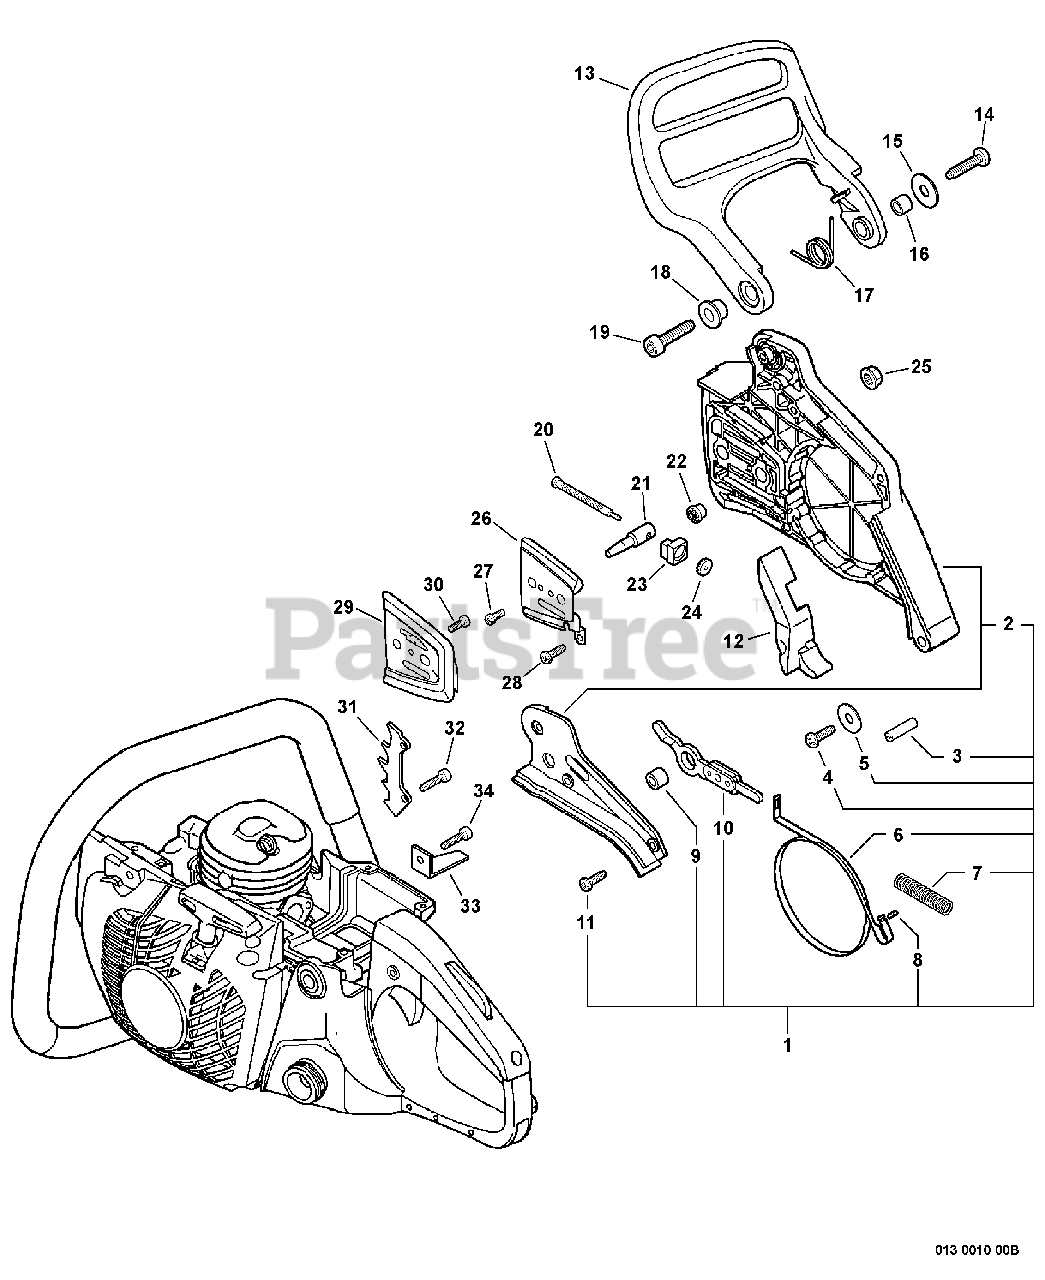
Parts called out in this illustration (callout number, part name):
1	CHAIN BRAKE ASSY - ORANGE
2	SPROCKET GUARD KIT
3	PIN - SPRING
4	SCREW - 4X16
6	BAND, BRAKE
8	PIN - 3X12
9	SPACER - 8
10	CONNECTOR, BRAKE
11	SCREW - 4X12 -- TAPPING
12	CUSHION
13	LEVER, BRAKE
14	SCREW - 4X14
16	SPACER - 8
18	COLLAR - 10
19	SCREW - 5X30
20	SCREW, TENSIONER
21	TENSIONER, CHAIN
22	GEAR - PINION
23	COLLAR - 8
24	GEAR - BEVEL
25	NUT - FLANGE
26	PLATE, GUIDE - OUTER
27	SCREW - 3X6
28	SCREW - 4X12 -- TAPPING
29	PLATE, GUIDE - INNER
30	SCREW - 4X6
32	SCREW - 5X12
33	CATCHER, CHAIN
34	SCREW - 5X14
